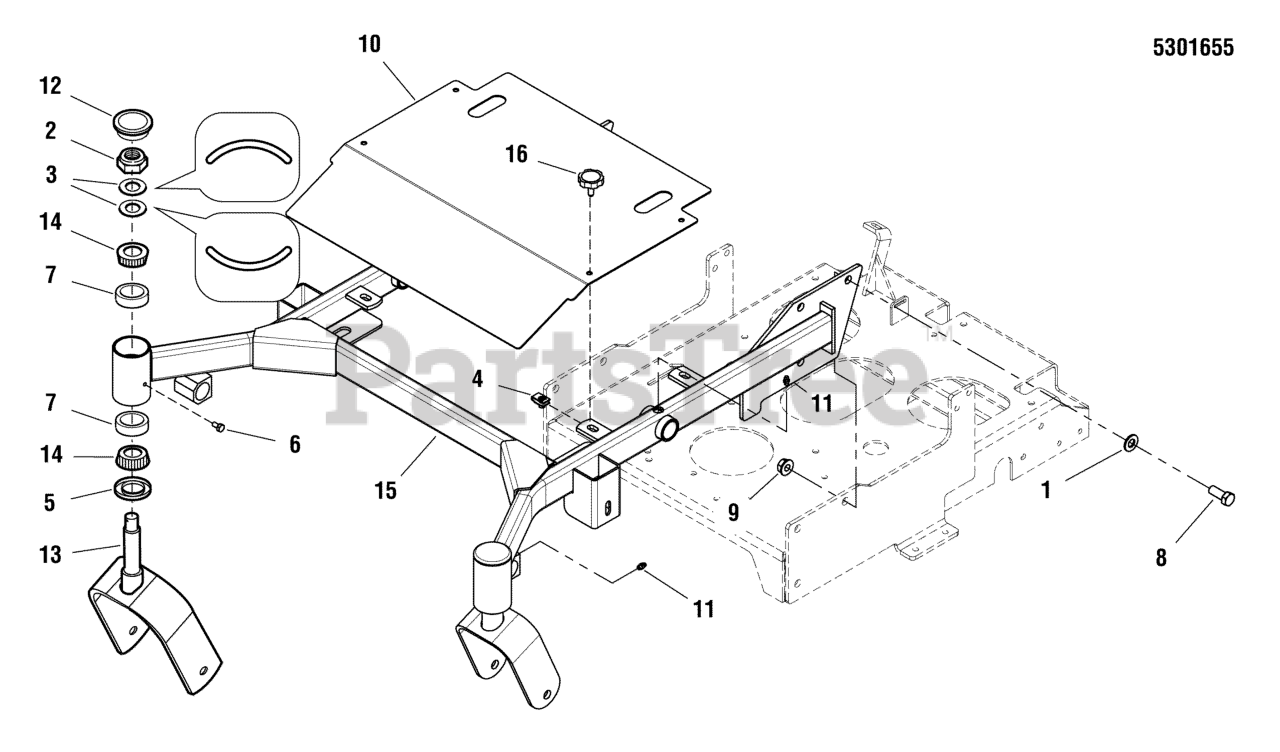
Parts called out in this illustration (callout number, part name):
1	WASHER, 1/2 SAE
2	NUT, 3/4-16, HEX JAM NYLON LOCK
3	WASHER, BELLEVILLE - 1.500 X .755
4	BODY CLIP, 5/16-18 -1/4 MATERIAL
5	SEAL, GREASE
6	BOLT, 1/4-28 X 1/2, GD5 YZ
7	CUP, BEARING (SV)
8	BOLT, 1/2-13 X 1-1/4 GD5 CZ
9	NUT, Hex Flange, Nylock, 1/2-13
10	GUARD, DECK LIFT, 48 - RED
11	GREASE FITTING, 1/4-28 STRAIGHT
12	CAP, GREASE, LOW PROFILE
13	WELD, CASTER YOKE, SNP DD - RED
14	BEARING, TAPERED ROLLER, 1"
15	WELD, FRONT FRAME, HYDRODRIVE1648 - RED
16	KNOB, 5/16-18 X 1.00 ROSETTE, BLK
